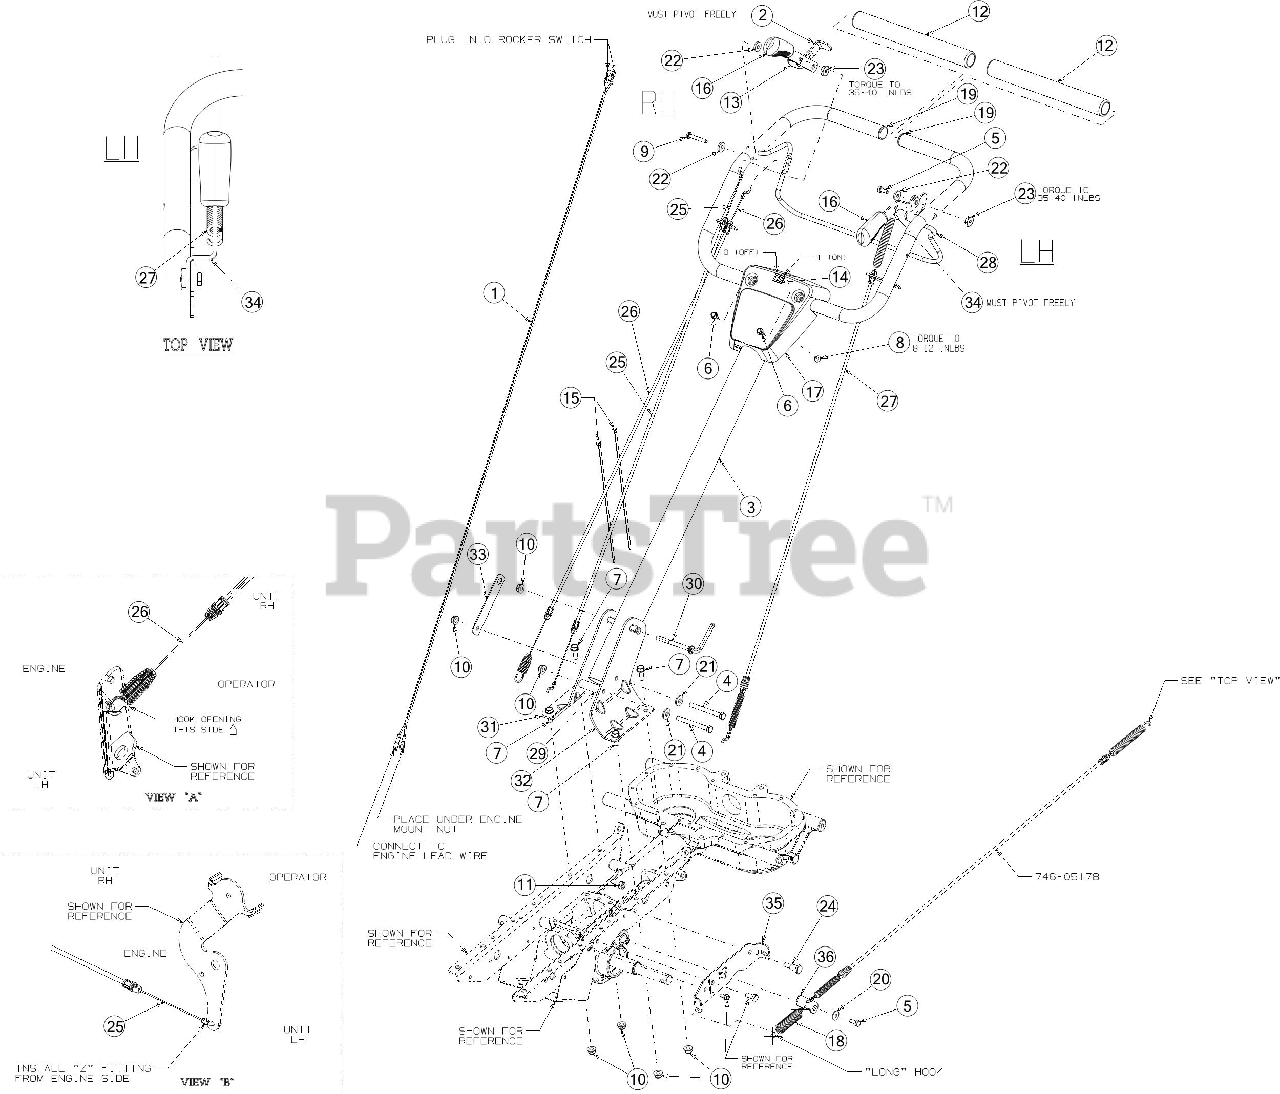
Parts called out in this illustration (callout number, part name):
1	HARNESS ADAPTER ASSEMBLY
2	REVERSE HANDLE ASSEMBLY
3	HANDLE ASSEMBLY
4	HEX SCREW 5/16-18 x 3.00
5	SCREW 1/4-20 x .62 SPEC GR5
6	SCREW 1/4-20 X.500
7	SCREW 5/16-18 x .875 GR5
8	SCREW #10-16 x .375
9	BOLT 1/4-20X1.62 GR5
10	FLANGE LOCK NUT 5/16-18
11	HEX NUT
12	FOAM GRIP .970 x 11.0
14	ROCKER SWITCH
16	BRAKE HANDLE GRIP
17	HANDLE COVER W/SWITCH HOLE
18	EXTENSION SPRING
20	SPRING WASHER BELL
21	BELLVILLE WASHER .827 x .331 x .098
22	FLAT WASHER
23	SHOULDER SPACER
24	SHOULDER SCREW
25	REVERSE CABLE
26	FORWARD CABLE
27	NEUTRAL CABLE
30	CRANK ADJUST HANDLE
31	HANDLE BRACKET (RH)
31	HANDLE BRACKET (LH)
32	HANDLE BRACKET (LH)
33	RETURN BRACKET
34	NEUTRAL HANDLE
35	NEUTRAL CABLE BRACKET
36	PIVOT LEVER
